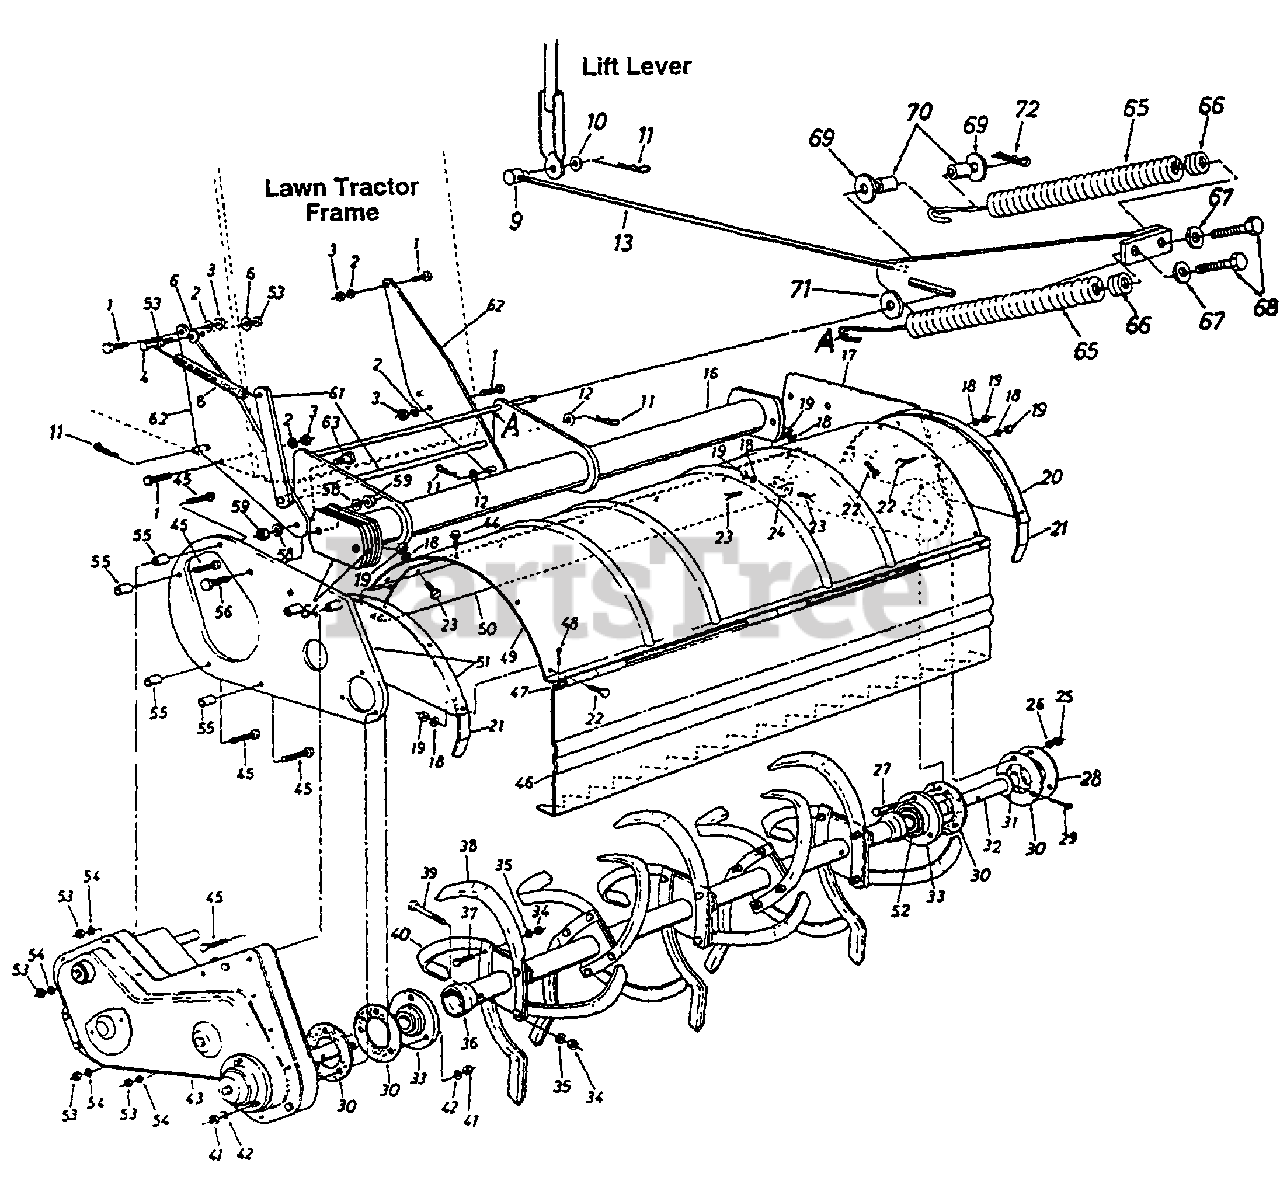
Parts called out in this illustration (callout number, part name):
1	Hex Bolt 3/8-24 x .88" Lg.
2	L-Wash. 3/8" l.D.- H.D.
3	Hex Nut 3/8-24 Thd.
4	Hex Bolt 1/4-20 x 1.25" Lg.
6	Bell-Wash. 1/4" I.D.
8	Ext. Spring 7.75" Lg.
9	Adjustment Ferrule 1/2-13 Thd.
10	Fl-Wash .64" I.D. x 1.24" O.D. x .06"
11	Intern. Cotter Pin 1/2" Dia.
12	Fl-Wash .51" I.D. x 1.0" O.D. x .06"
16	Pivot Bracket Assembly
19	Hex Nut 5/16-24 Thd.
23	Hex Bolt 5/16-24 x .62" Lg.
24	Chute Pivot Bracket
25	Hex L-Nut 5/16-18 Thd.
27	Hex Bolt 5/16-18 x 1" Lg. (Grade 5)
30	Gasket for Brg. Housing
31	Fl-Wash. 1.25" I.D. x 2.0" O.D. x .06"
32	Tine Shaft 1.25" Dia. x 6.25" Lg.
33	Bearing Housing w/Bearing
43	Chain Case Ass'y. Comp.
44	Hex TT-Tap Scr. 5/16-18 x .62" Lg.
45	Hex Bolt 1/4-20 x 2.75" Lg.
48	Cotter Pin 1/8" Dia. x 1" Lg.
53	Hex Nut 1/4-20 Thd.
54	L-Wash. 1/4" I.D.
55	Spacer .28" I.D. x .62" O.D. x .9" Lg.
56	Hex Bolt 1/2-20 x 1.5" Lg.
58	L-Wash. 1/2" I.D.
59	Hex Nut 1/2-20 Thd.
61	Idler Brkt. Support Arm Ass'y.
64	Support Plate
65	Helper Spring
66	Spring Insert
67	Fl-Wash .34" I.D. x .68" O.D.
68	Hex Bolt 5/16-18 x 3.25" Lg.
69	Fl-Wash .51" I.D. x 1.5" O.D.
70	Split Spacer.505" l.D. x .57" Lg.
71	Fl-Wash .531" I.D. x 1.25" O.D.
72	Internal Cotter Pin 1/2" Dia.
